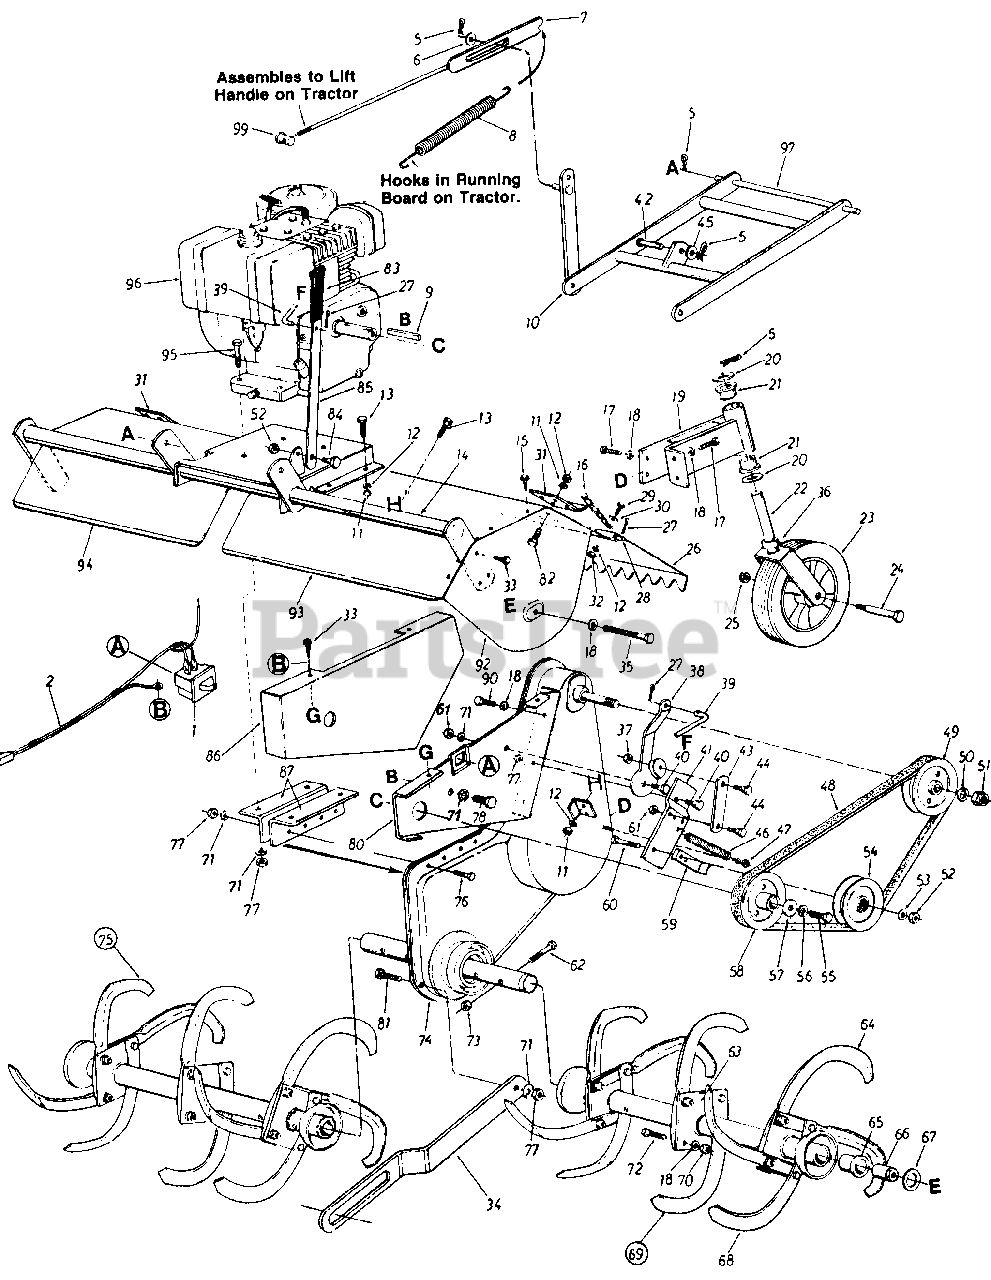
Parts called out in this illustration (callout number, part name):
1	Safety Switch
2	Wire Harness
5	Internal Cotter Pin
6	Fl-Wash. 1/2" I.D. x .93" O.D.
9	Sq. Key 1/4" x 1/4" x 2.00" Lg.
12	L-Wash. 1/4" I.D.
13	Hex Bolt 1/4-28 x .62" Lg.
16	#2 Dog Chain x 20" Lg.
17	Hex Wash. Hd. Self-Tap Scr. 318-24 x .75" Lg.
18	L-Wash. 3/8" I.D.
21	Flange Bearing 3/4" I.D. x 1.001' O.D.
24	Shoulder Bolt .623" I.D. x 3 . 62 " Lg .
25	Hex Cent. L-Nut 7/16-14 Thd.
28	L.H. Flap Rod
29	Hex Bolt 1/4-20 x .62" Lg.
30	Fl-Wash. 1/4" I.D.
33	Hex Wash. Hd. Self-Tap Scr. 1/4" x .62" Lg
36	Spacer .752" I.D. x 1.25"O.D.
37	Hex Cent. L-Nut 5/16-18 Thd.
40	Shoulder Bolt 7116" Dia. x 1.75" Lg.
45	Fl-Wash. .50" I.D. x 1.0" O.D. x .06
46	Extension Spring .62" O.D. x 6.12" Lg.
47	Hex Crown Nut 3/8-24 Thd.
48	"V"-Belt (Kevlar)
49	1/2" "V"-Pulley 4.75" O.D. x .625" Bore
50	L-Wash. 5/8" I.D.
51	Hex Ins. L-Nut 5/8-18 Thd.
52	Hex Cent. L-Nut 3/8-16 Thd.
53	Fl-Wash. 3/8" I.D.
54	Idler Pulley 4.0" O.D.
55	Hex Bolt
56	L-Wash. 7/16" I.D.
57	Fl-Wash. 7/16" I.D. x 1.38"
58	1/2" "V"-Pulley .475" O.D. x 1.00" Bore
61	Hex Cent. L-Nut 5/16-18 Thd.
62	Hex Bolt 7/16-14 x 2.00" Lg.
66	Spacer
67	Thrust Wash. 1/2" I.D. x 1.55"
71	L-Wash. 5/16" I.D.
72	Hex Bolt 3/8-24 x 1.5" Lg.
73	Hex Cent. L-Nut 7/16-14 Thd.
77	Hex Nut 5/16-18 Thd.
78	Hex Bolt 5/16-24 x .62"
80	Clutch Support Bracket
81	Shld. Bolt .435 Dia. x .265 5/16-18 Thd.
82	Hex Bolt 1/4-28 x .75" Lg.
83	Plastic Grip
84	Shoulder Bolt .498 Dia. x .212 Lg.
96	8 H.P. Engine
97	Hitch Rod
99	Ferrule
